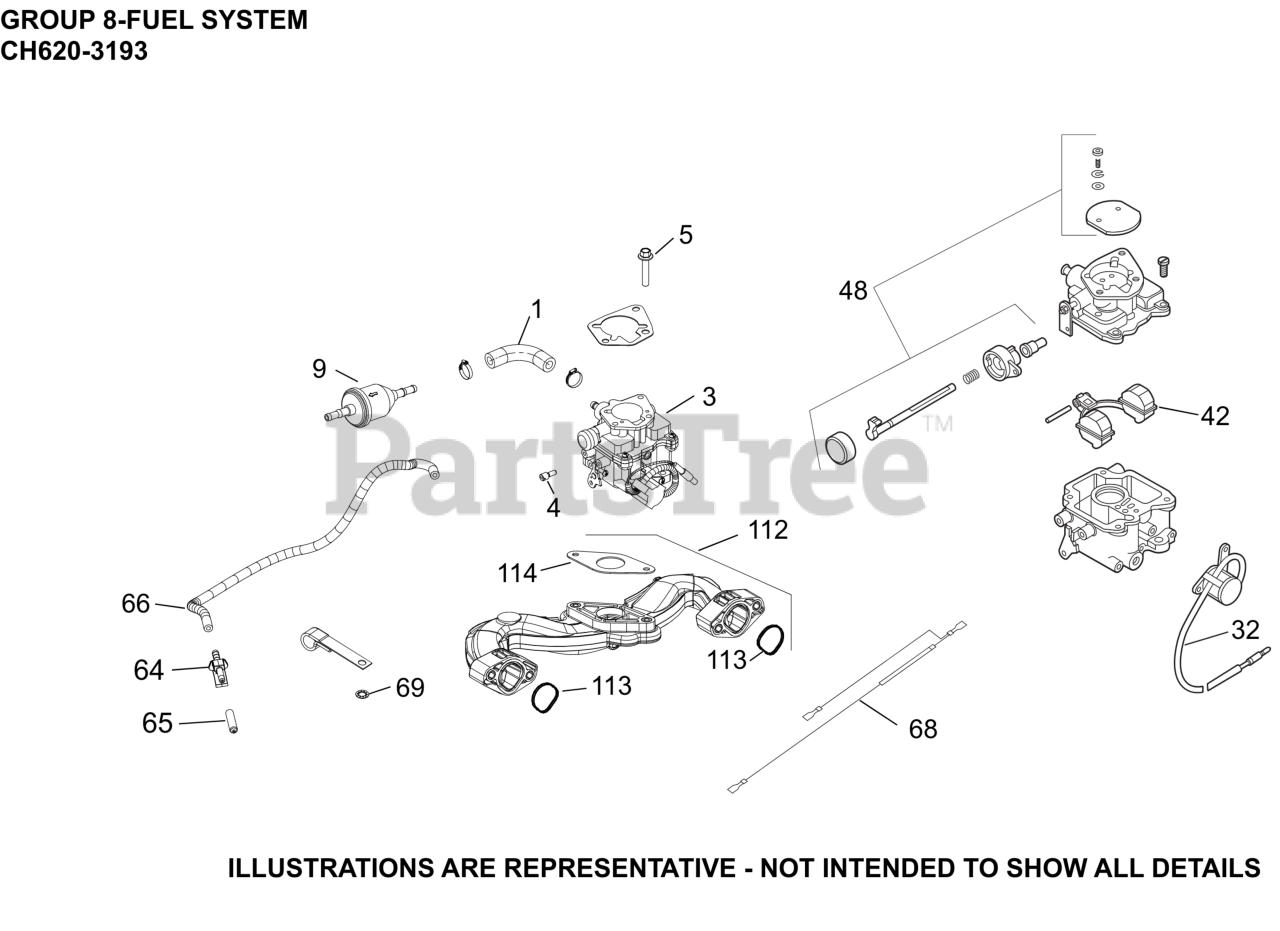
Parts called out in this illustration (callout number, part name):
1	HOSE,LW PERM.FUEL 24.00"-USE 25 111 81-S
3	KIT, CARBURETOR COMPLETE
4	SCREW, THROTTLE STOP
5	SCREW, FLG M6X1.0X25
9	FILTER, FUEL
32	KIT, SOLENOID
42	KIT, REPAIR FLOAT
48	KIT, REPAIR CHOKE
64	CONNECTOR, EVAPORATIVE
65	CAP, MASKING
66	HOSE, EVAPORATIVE 20"- (#24326143S)
68	LEAD, GROUND
69	WASHER, INT TOOTH LOCK 1/4"
112	INTAKE MANIFOLD W/GASKETS
113	O-RING, INTAKE PORT
114	GASKET, CARBURETOR (PIM, CH)
NI	KIT, HIGH ALT (4000-8000 FT)
NI	KIT, HIGH ALT (8,000+ FT)
NI	KIT, REPAIR CARBURETOR
